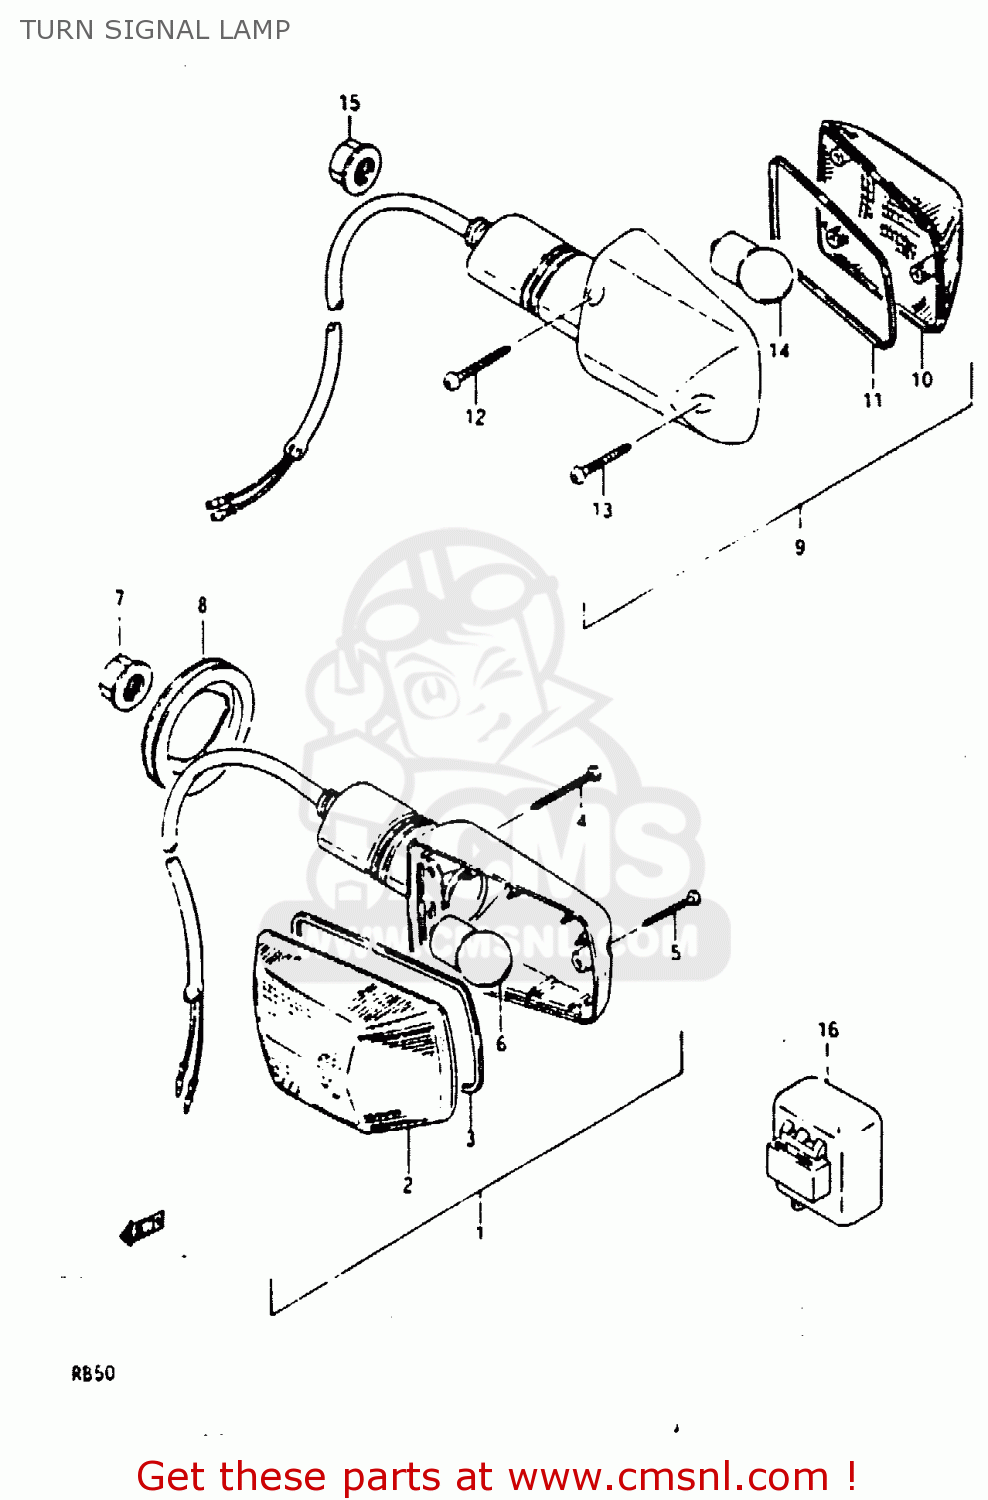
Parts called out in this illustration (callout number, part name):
1	LAMP ASSY,FR TURN SIGNAL
2	LENS,TURNSIGNAL
3	GASKET (NAS)
4	SCREW(3X30)
5	SCREW
6	BULB(6V8W,STANLEY,A4115)
7	NUT
8	GROMMET,TURNSIGNAL LAMP
9	LAMP ASSY,FR TURN SIGNAL
10	LENS,TURNSIGNAL
11	GASKET (NAS)
12	SCREW(3X30)
13	SCREW
14	BULB(6V8W,STANLEY,A4115)
15	NUT
16	RELAY,TURN SIGNAL
